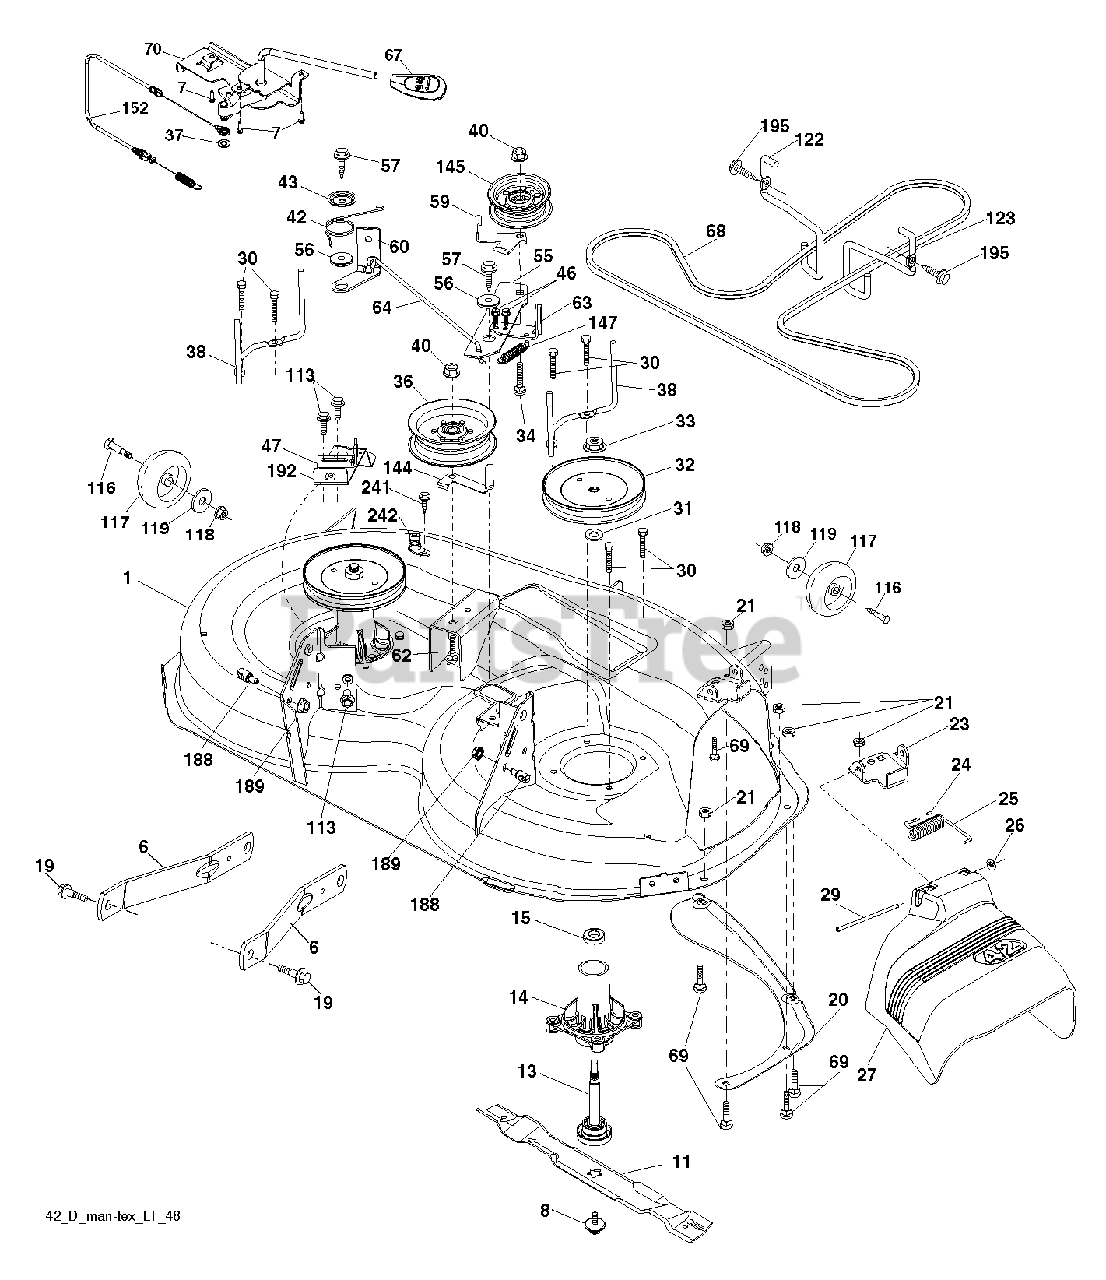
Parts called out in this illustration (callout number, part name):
6	ARM.SUSPENSION.MOWER.R
7	SCREW.#10 X 0.750.BOS THREAD
8	BOLT.WASHER.ASM.7/16-2
11	42" HI-LIFT BLADE
13	SHAFT.ASM.MDRL.N/GREASE.38
14	HOUSING MANDREL
15	BEARING
19	BOLT.SHOULDER
23	BRKT.DEFLECTOR.38"2005
24	CAP-SLEEVE LT
25	SPRING.TORSION.DEFLECT
26	NUT PUSH M
29	HINGE ROD
30	SCREW, WASHER HEAD
33	NUT.FLANGE.LOCK.TOP
37	WASHER
46	SCREW 1/4-20X5/8
56	SPACER.RETAINER
57	SCREW 3/8-16X1
59	GUARD
69	BOLT
116	BOLT M
117	WHEEL GAGE.HALF.SPOKED
145	PULLEY.IDLER.48"PRIMARY
188	STUD.FASTNER.W/D.ANTI-
189	NUT LOCK HEX FLANGE 5/16-18
195	SCREW, 3/8-16X3/4
242	PORT.WASHOUT
